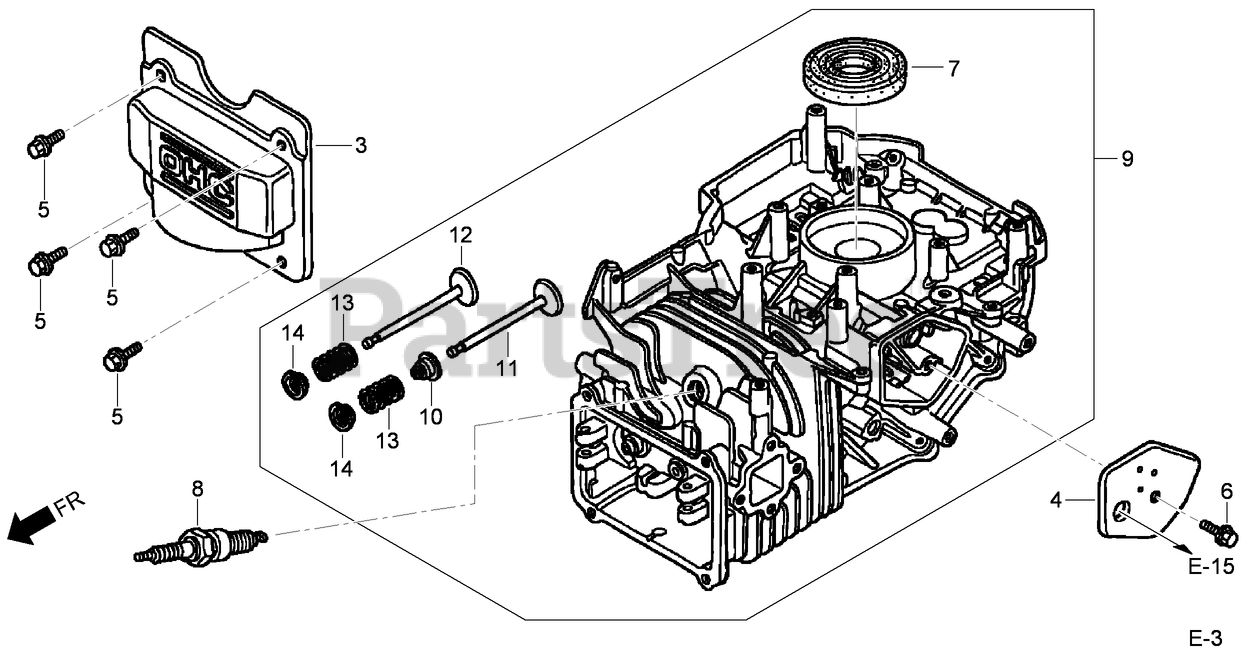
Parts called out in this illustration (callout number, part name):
3	COVER-HEAD, CYLINDER
3	COVER-HEAD
4	COVER-BREATHER (BREATHER VALVE ASM)
5	BOLT-FLANGE (6X12) (C T200)
6	BOLT-FLANGE (6X14) (C T200)
7	SEAL (25.4X62X6)
8	SPARK PLUG (B P R 6E S) (N G K)
9	CYLINDER ASM
10	SEAL-STEM, VALVE
11	VALVE-INTAKE (ROCKNEL) (engine serial numbers up to 6330748)
11	VALVE-INTAKE (engine serial numbers starting at 6330749)
12	VALVE-EXHAUST
13	SPRING-VALVE
14	RETAINER-SPRING, VALVE
